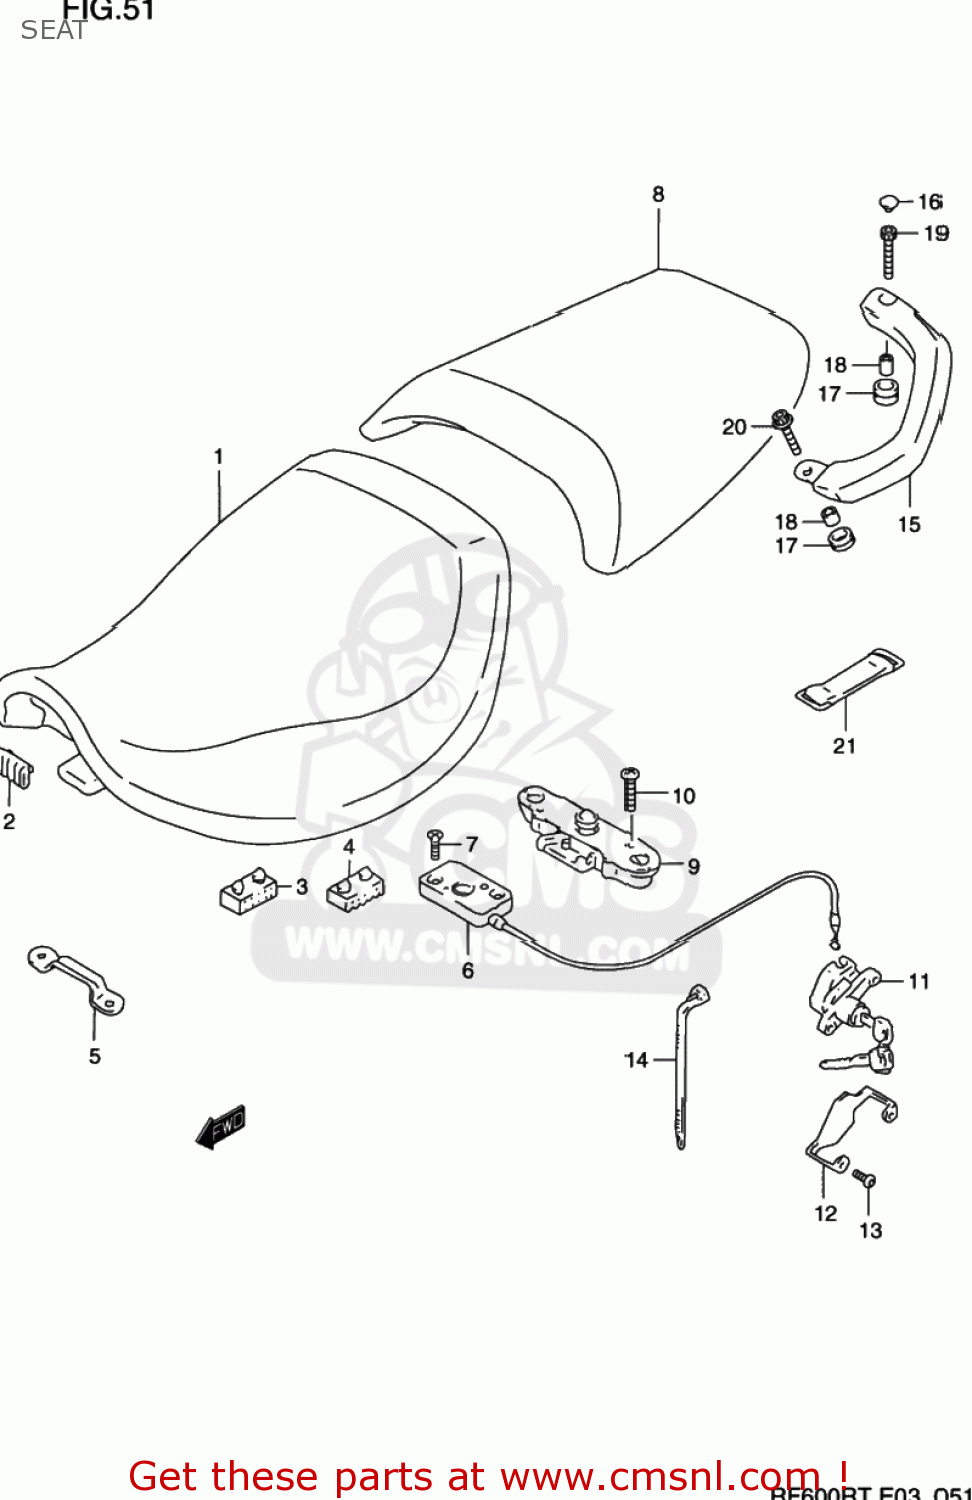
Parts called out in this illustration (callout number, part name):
1	SEAT ASSY
2	CUSHION,BATTERY
3	CUSHION,SEAT(40X20X6)
4	CUSHION,SEAT(40X20X15)
5	PLATE,SEAT FR HOOK
6	BRACKET COMP,SEAT SUPPORT
7	SCREW
8	SEAT ASSEMBLY,PILLION
9	BRACKET COMP,SEAT SUPPORT
10	SCREW 6X30
11	LOCK SET,SEAT & HELMET
12	PLATE,SEAT LOCK GUARD
13	SCREW(6X12)
14	CLAMP(L:125)
15	HANDLE,PILLION RIDER,R(BLACK)
16	CAP(OD:14.5)
17	CUSHION
18	SPACER(8.4X12X12)
19	BOLT
20	BOLT
21	BAND
